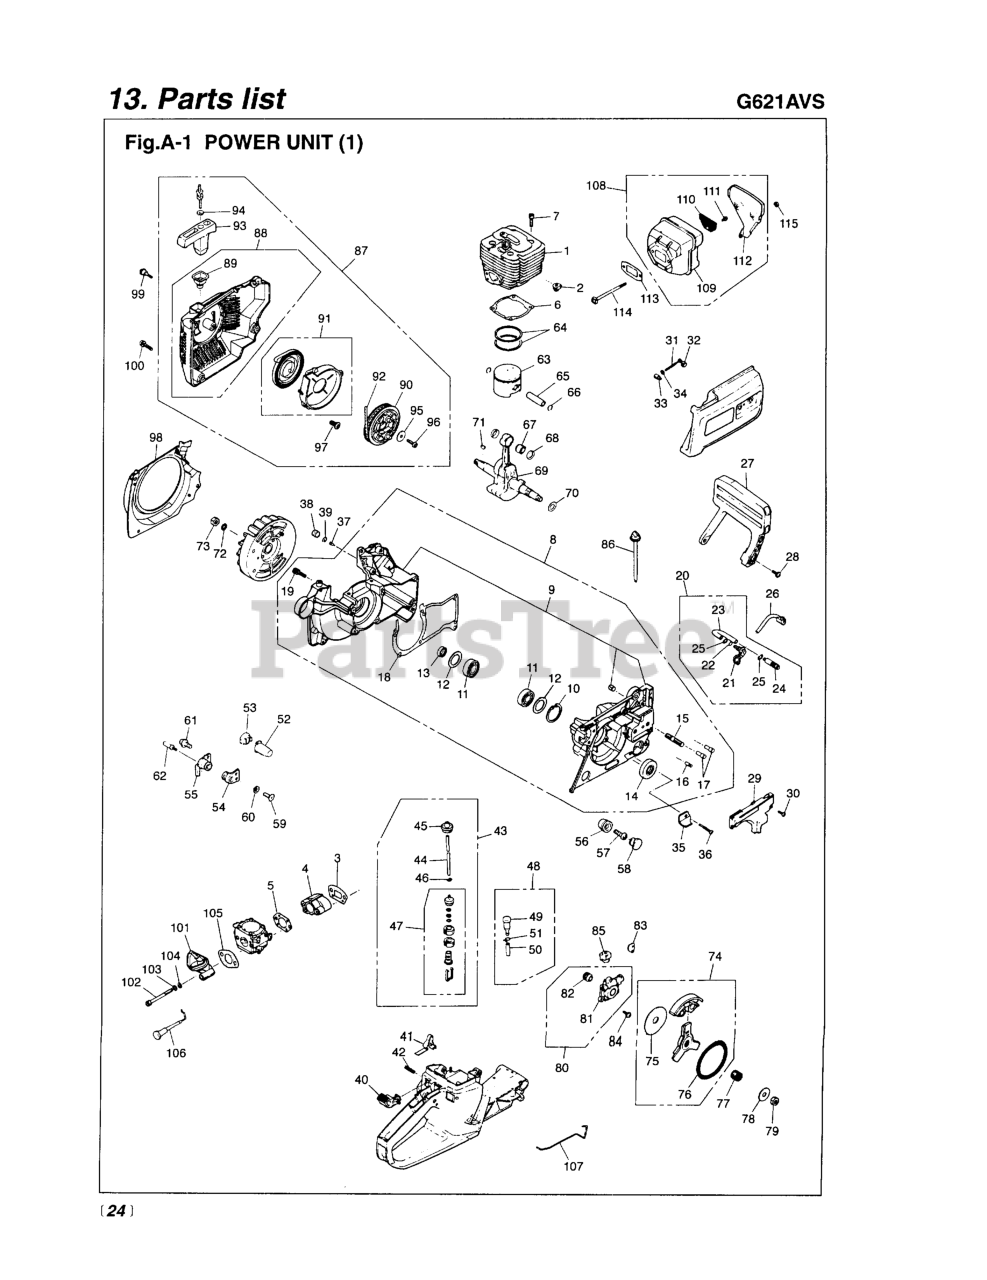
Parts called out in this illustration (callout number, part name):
2	GROMMET
3	2616-14112 (RPLS-14110)
4	INSULATOR
6	GASKET, CYLINDER (RPLS.-14210)
7	BOLT M5 x 20 (RPLS -12280)
10	RING, SNAP, M35 X 1.5
12	RING
13	SEAL, OIL
15	STUD (RPLS 0205-50825)
16	PIN
17	PIN
19	BOLT M5 x 20 (RPLS -12280)
20	OIL PIPE COMP
21	PIPE, OIL
24	WEIGHT
26	PIPE, OIL
29	COVER, BRAKE (RPLS -24411)
30	SCREW, M5 x 14
31	ADJUST SCREW
32	STOPPER, ADJUS
33	NUT (A)
34	WASHER, M5 X .8
35	CATCHER, CHAIN (RPLS -25210)
37	VALVE (RPLS -23120)
38	SEAL, BREATHER
39	CLIP
40	SWITCH LEVER
41	SPRING
42	PIN, SPRING
43	PIPE ASSEMBLY
44	PIPE, SUCTION
45	GROMMET
46	CLIP (REPLACES 2841-31280)
47	FILTER ASSY
48	BREATHER ASSEMBLY
49	BREATHER ASSY (RPLS 2630-31270
51	CLIP (REPLACES 2841-31280)
52	DAMPER (RPLS -35111)
53	CAP (RPLS -35120)
54	DAMPER (RPLS -35150)
55	DAMPER (REPLACES -35131)
56	DAMPER (RPLS 2670-35110)
57	SCREW
58	CAP
59	SCREW, M5 X 14
61	SCREW
63	PISTON
64	RING
65	PIN, PISTON
66	RING, SNAP
67	BEARING
68	WASHER (RPLS 1491-41510)
69	CRANKSHAFT (RPLS -42003)
70	SHIM (REPLACES 848-870-G000)
71	KEY
72	WASHER, M10 X 25
73	NUT
74	CLUTCH ASSY (RPLS -51200)
75	PLATE
76	SPRING (RPLS -51230)
77	BEARING
78	WASHER
79	NUT
82	GEAR, WORM
83	GASKET, PUMP
84	SCREW, M5X20 (RPLS.1400-75510)
85	GROMMET (RPLS -55451)
86	SHAFT
87	STARTER ASSY (RPLS. -75003)
88	CASE (RPLS -75101)
89	GUIDE
90	REEL
91	SPRING COMP (RPLS. -75301)
92	ROPE
93	KNOB, STARTER
96	SCREW
98	COVER
100	SCREW
101	MANIFOLD (RPLS -82112)
103	WASHER, SPRING M4 x 1.3
104	WASHER, M5 X .8
106	ROD, CHOKE
107	ROD (RPLS 3356-82411)
109	MUFFLER (REPLACES 3359-15111)
110	ARRESTER, SPARK
111	SCREW, M4 X 8
113	GASKET
114	BOLT
